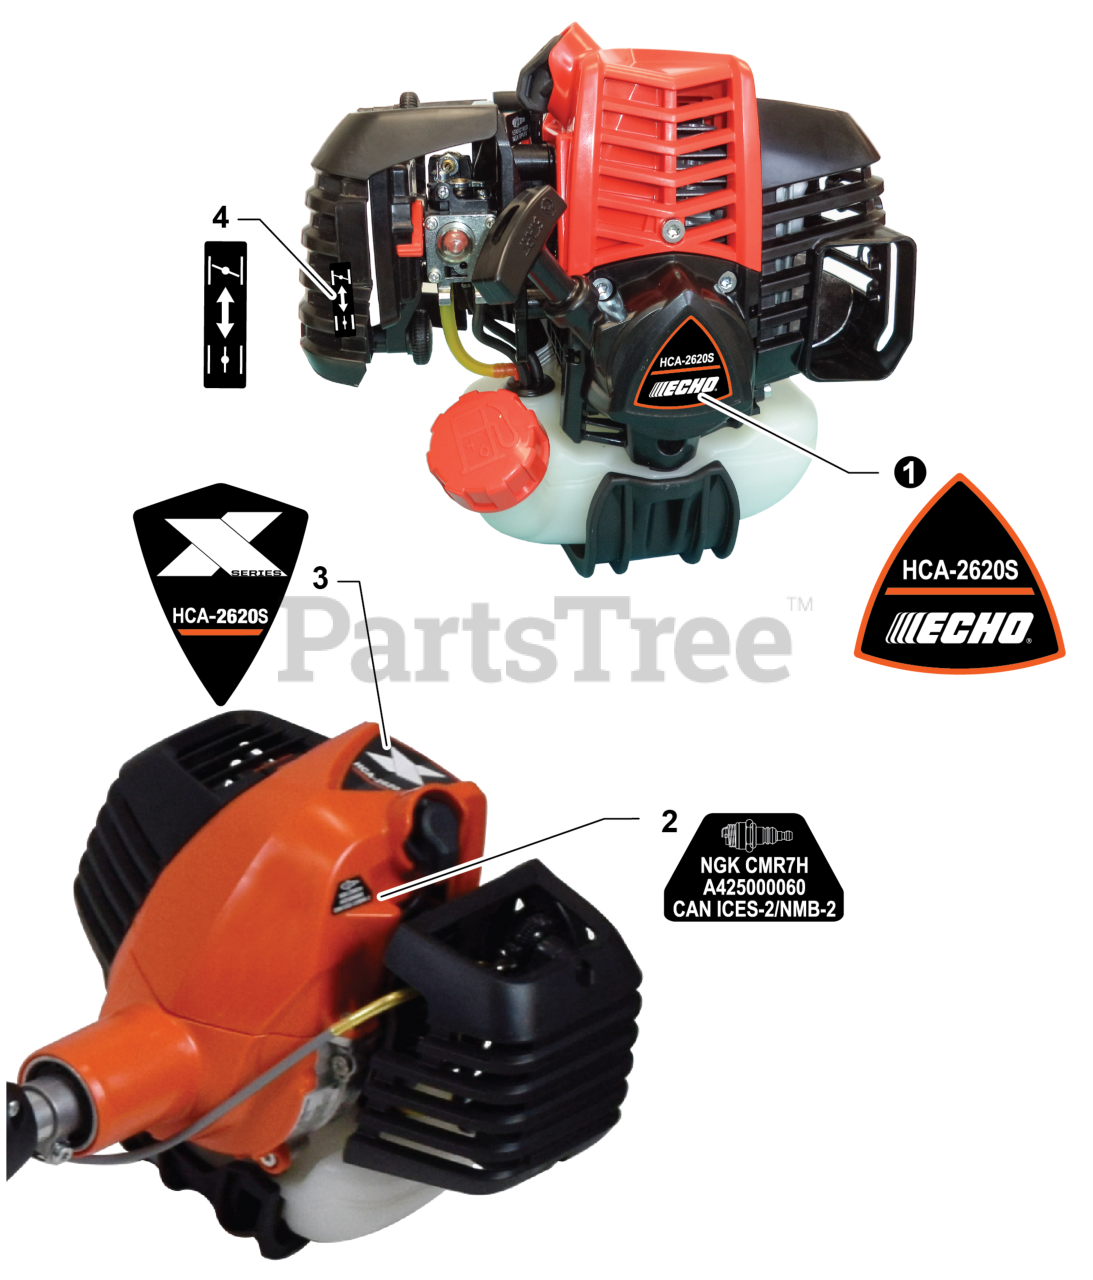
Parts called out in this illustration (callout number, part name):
1	LABEL - RECOIL STARTER - HCA-2620S
2	LABEL - SPARK PLUG - CMR7H
3	LABEL - MODEL HCA-2620S
4	LABEL - CHOKE
